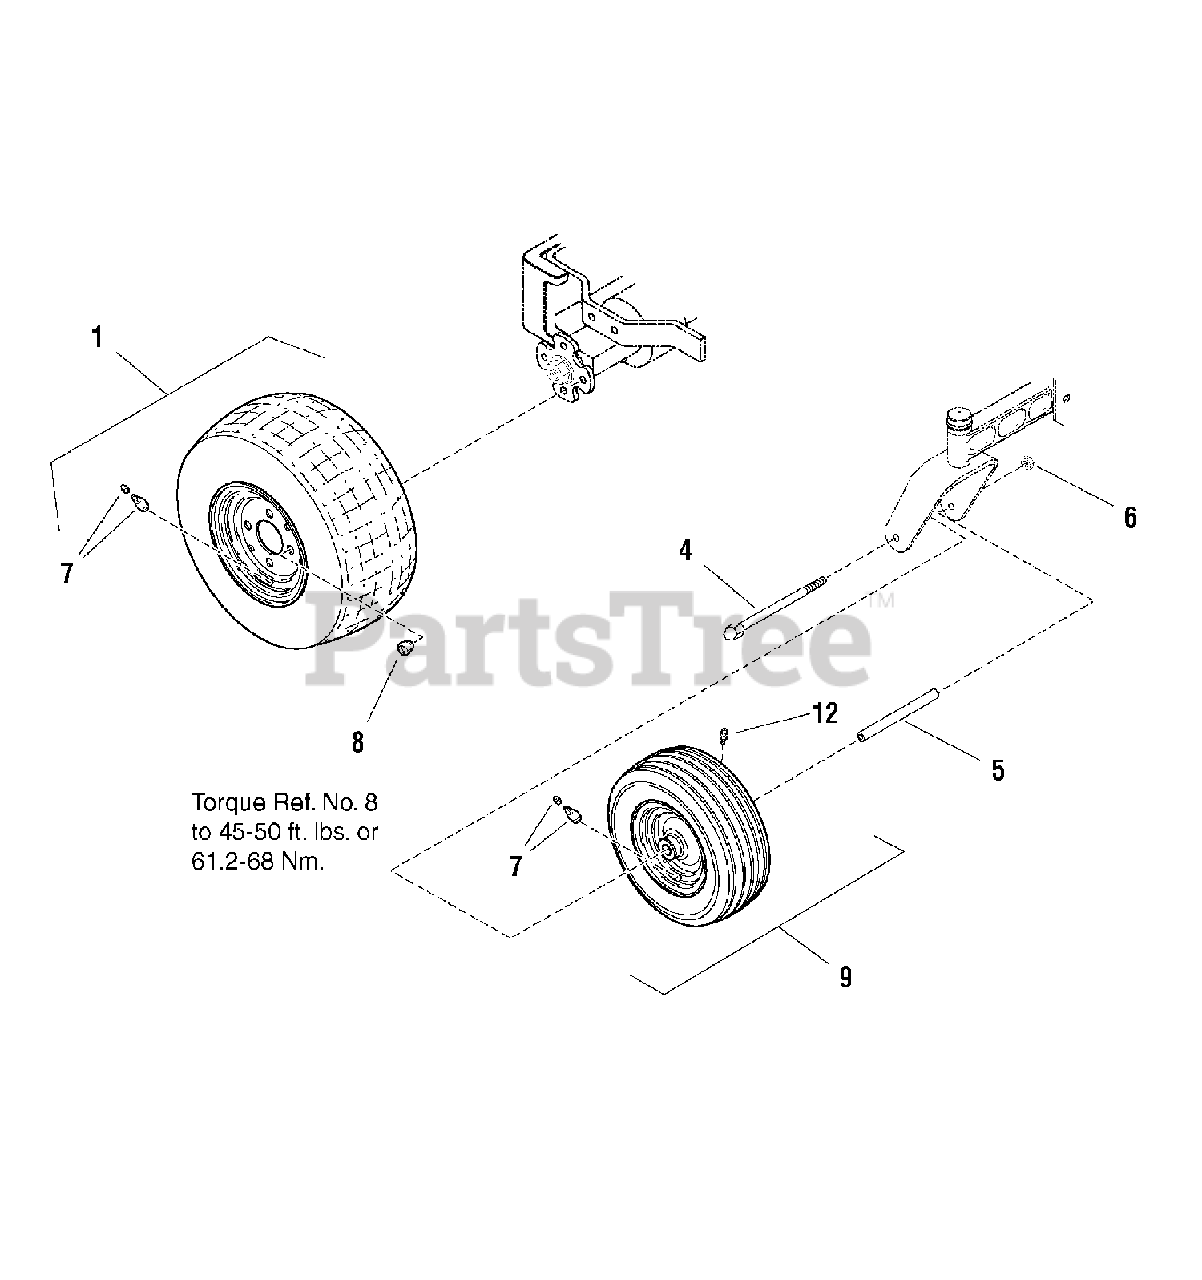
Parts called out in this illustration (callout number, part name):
1	WHEEL & TIRE ASSEMBLY, 18 x 8.50 - 8, Turf 4 Ply, K500
4	CAPSCREW, 7/16C X 6, GR5, Hex Head, YZ
5	TUBE, .625 OD, 4.53 LG, .625 OD, Caster Wheel Spacer
6	NUT, 7/16C GR5 Hex Center Lock ZP
7	VALVE STEM & CAP
8	NUT, 7/16-20, Hex Lug
9	WHEEL & TIRE ASSEMBLY, 11 x 4.0 - 5
12	FITTING, .250-28, Lube, Taper Thread, Straight, Ball Check
